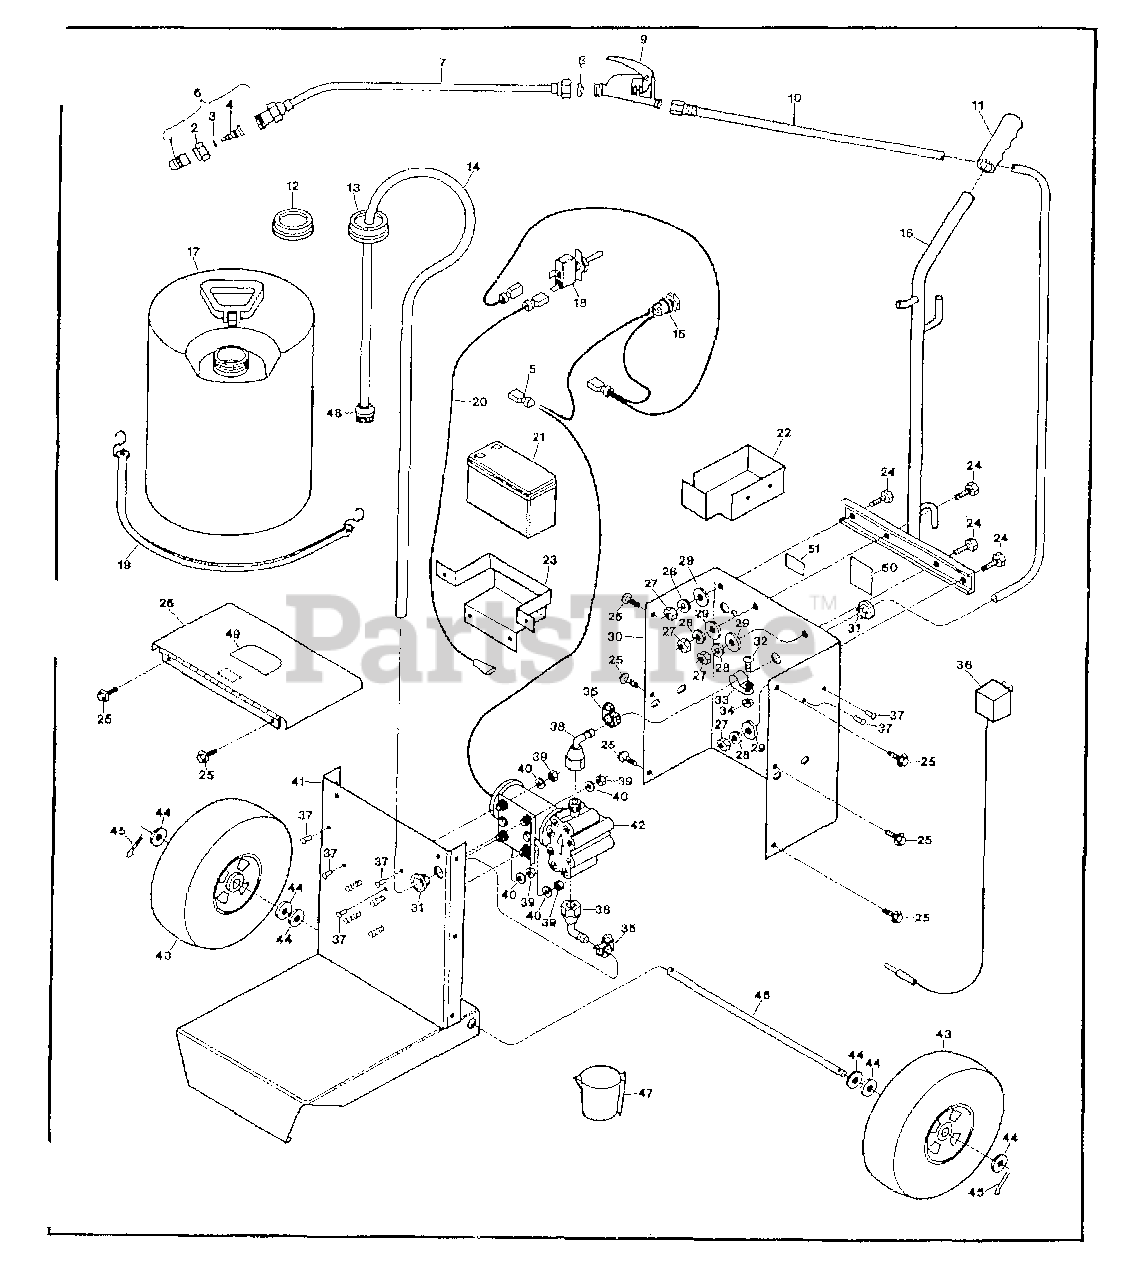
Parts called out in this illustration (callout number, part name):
1	TIP-BRASS BODY #5457 10835
2	ASSM-ADJ CONE W5500
3	RING-O 5500 CONE JET
4	ASSM-ADJ CONE W5500
5	TERMINAL
6	ASSM-ADJ CONE W5500
7	EXTENSION-SPRAY 10825
8	WASHER-TEFLON/BRASS 10842
9	VALVE-SHUT OFF PISTOL 10824
10	HOSE W/FITTINGS 10845
11	GRIPS-HANDLEBAR
12	CAP-E/S TANK 10868
13	CAP W/HOLE 10869
14	HOSE-1/4" X 4' 10841
15	KIT-CHARGING 10871
16	ASSM-HANDLE
17	TANK-REPL
18	SWITCH-TOGGLE 10830
19	STRAP-RUBBER 10826
20	WIRE-ON/OFF-SWITCH PUMP
21	BATTERY-12V EL SPRAYER 10815
22	BRKT-ACCESSORY
23	ASSM-BATTERY BRKT
24	SCR-HH 5/16-18X1.0 G5 ZP
25	SCR-HW M10-24X.375 ZP
26	LID W/DECAL
27	NUT-HEX 5/16-18 ZP
28	WASHER-LK .312 ZP
29	WASHER-1.25X.375X.1 ZP
30	HSG-CHASSIS W/DECALS
31	BUSHING-SNP 10827
32	SCR-RH M10-32X.5 MACH
33	CLAMP-CABLE 10828
34	NUT-HH M10-32X.125
35	CLAMP-HOSE 10829
36	CHARGER-BATTERY EL SPRAYER
37	RIVET-POP 1/8-3/8 10840
38	SWIVEL-90 ELBOW 10843
39	NUT-HEX M10-24
40	WASHER-#10
41	ASSM-CHASSIS
42	PUMP-SHURFLO 11511 5GAL
43	ASSM-TIRE & WHEEL
44	WASHER-1.75X.625X.11
45	PIN-COTTER 3/32 X 1 1/4
46	AXLE-EL SPRAY 10847
47	CUP-MEASURING 8OZ 10833
48	STRAINER-EL SPRAYER 10832
49	DECAL-LOGO EL SPRAYER
50	DECAL-CHARGE 10817
51	DECAL-WARNING E/S 10818
